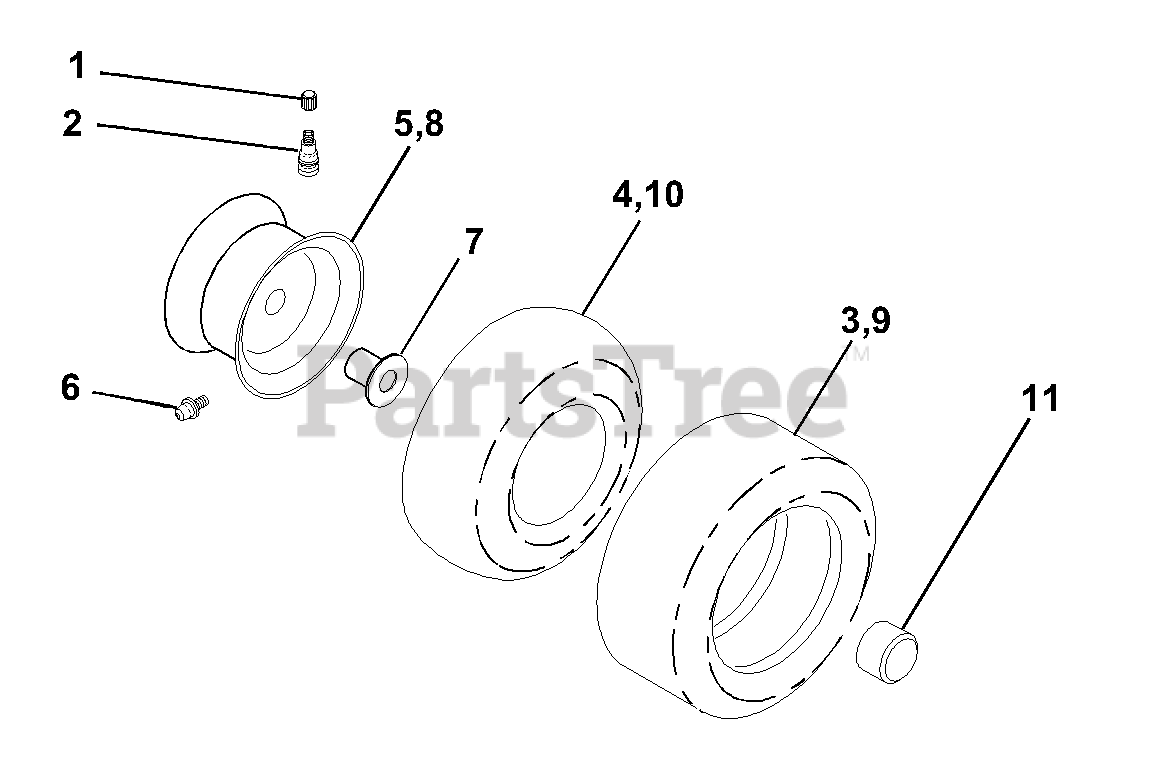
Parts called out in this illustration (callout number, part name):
1	Cap Valve Tire
2	Stem Valve
3	Tire F T 15 X 6 0 - 6 Service
4	Tube Front
5	Rim Asm 6"front Service
6	Fitting Grease
7	Bearing Flange
8	Rim Asm 8"rear Service
9	Tire R T 20x10-8 Service
10	Tube Rear
11	Cap Axle Blk 1 50 X 1 00
